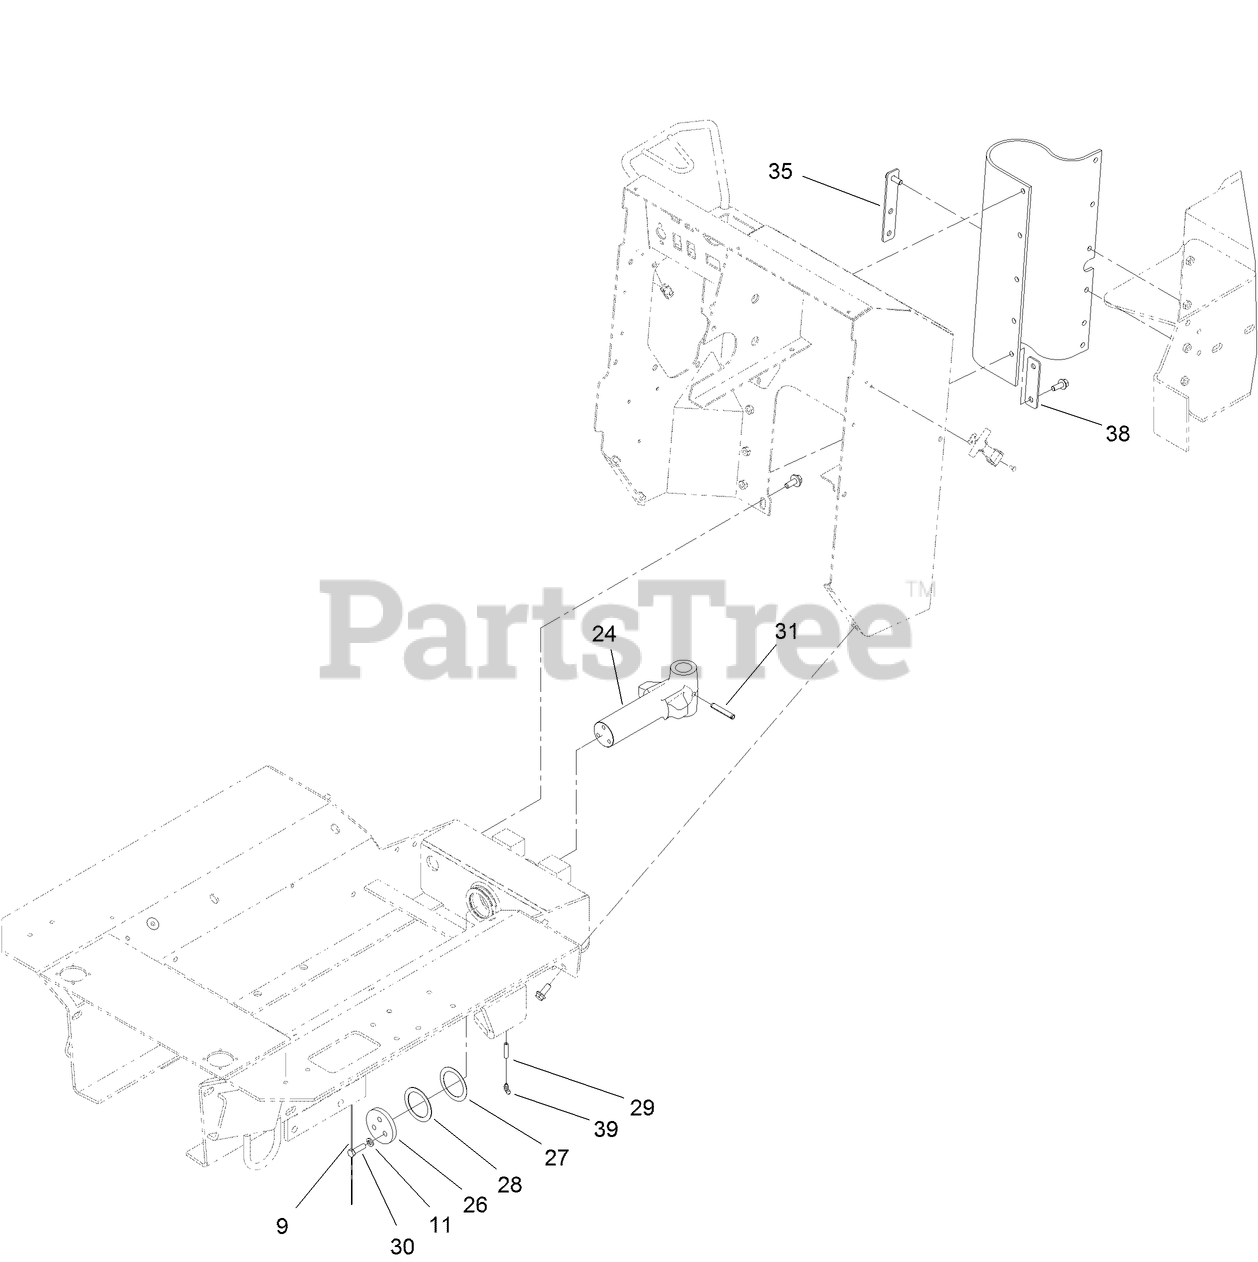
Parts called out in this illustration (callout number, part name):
9	WIRE-STEEL
11	WASHER-LOCK
24	PIVOT-ARTICULATION
27	SHIM-THIN
29	FITTING-LUBE
30	SCREW-HH
39	FITTING-GREASE
